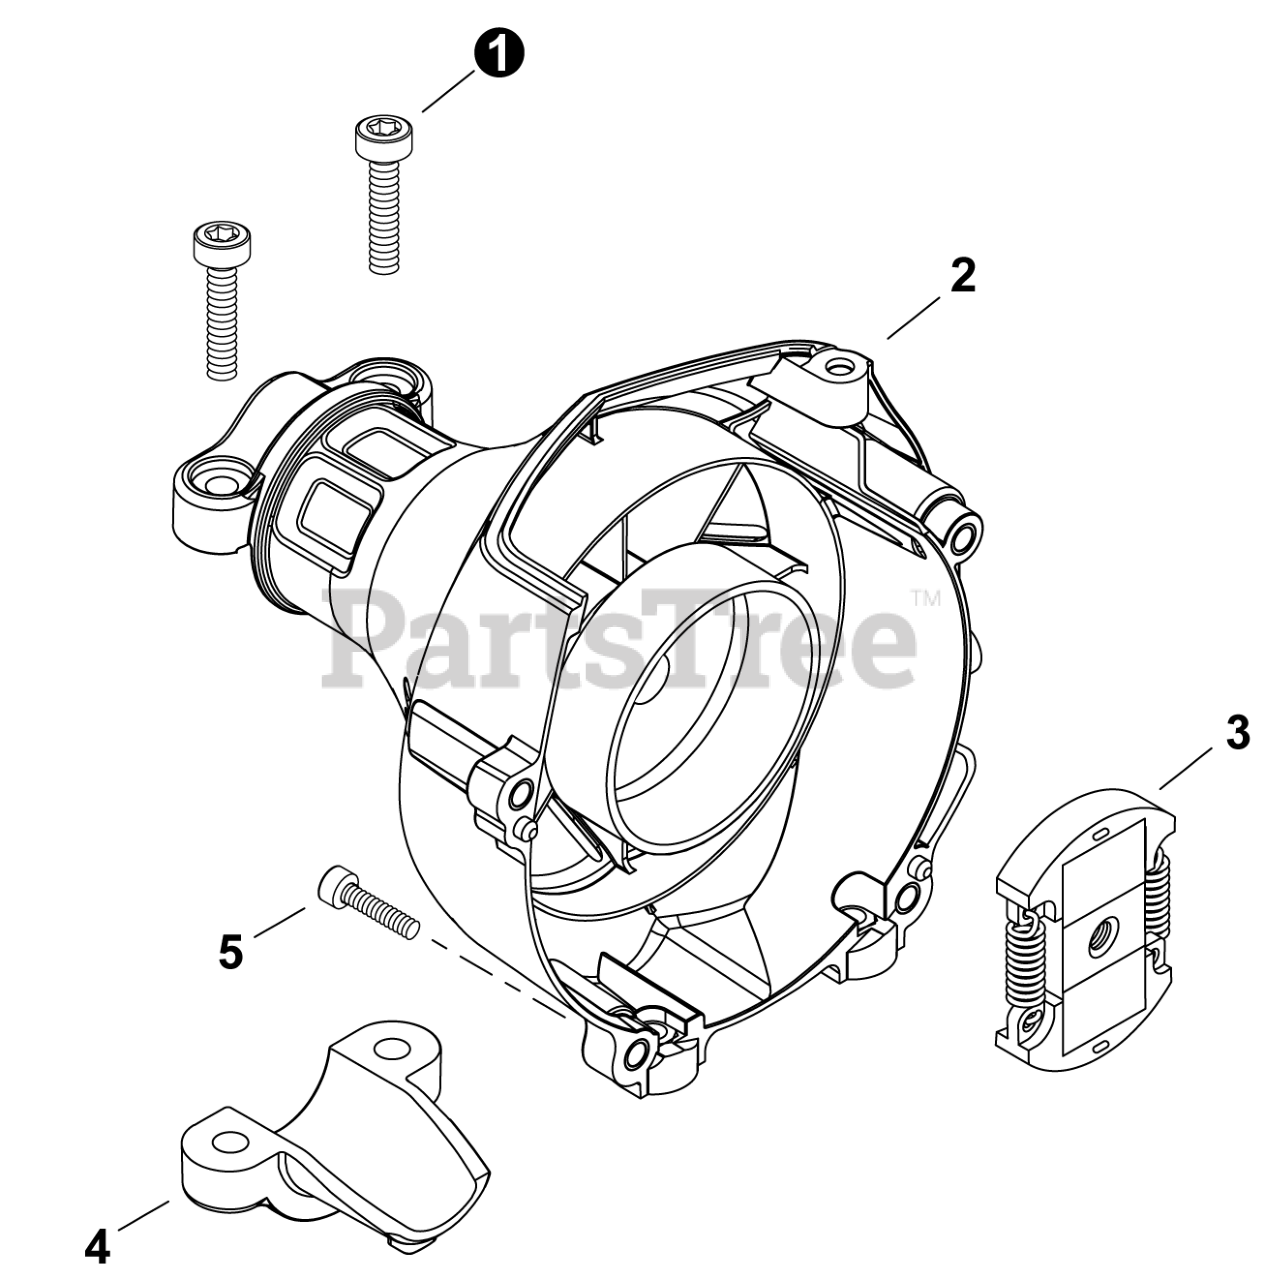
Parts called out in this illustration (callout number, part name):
1	BOLT, TORX 5x20
2	COVER ASSY, FAN
3	CLUTCH ASSY
4	HOLDER, MAIN PIPE - LOWER
5	BOLT, TORX 4x16
